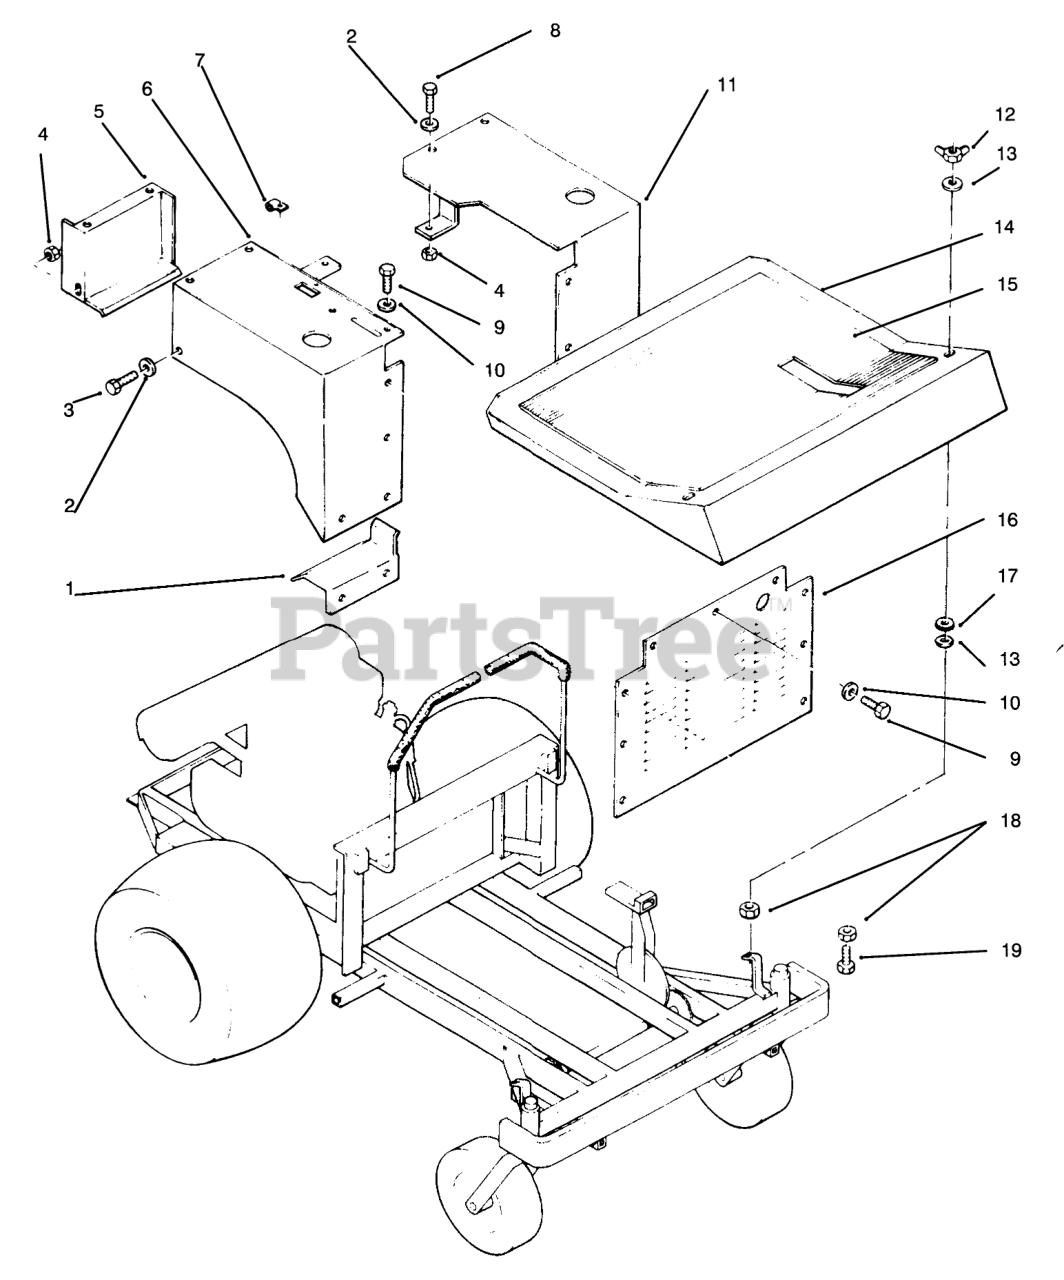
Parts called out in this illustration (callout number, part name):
1	Bracket-Fender Frt RH
2	WASHER-FLAT
3	SCREW-HH
4	NUT-LOCK, NI
5	Bracket-Fender Rear RH
6	FENDER WA RH R
7	J-CLIP
8	SCREW-HH
9	SCREW-HWH
10	WASHER-FLAT
11	Fender LH
12	WING NUT
13	WASHER-FLAT
14	Floor Pan
15	Black Carpet
16	Front Panel
17	WASHER
18	NUT-HEX
19	SCREW-HH
